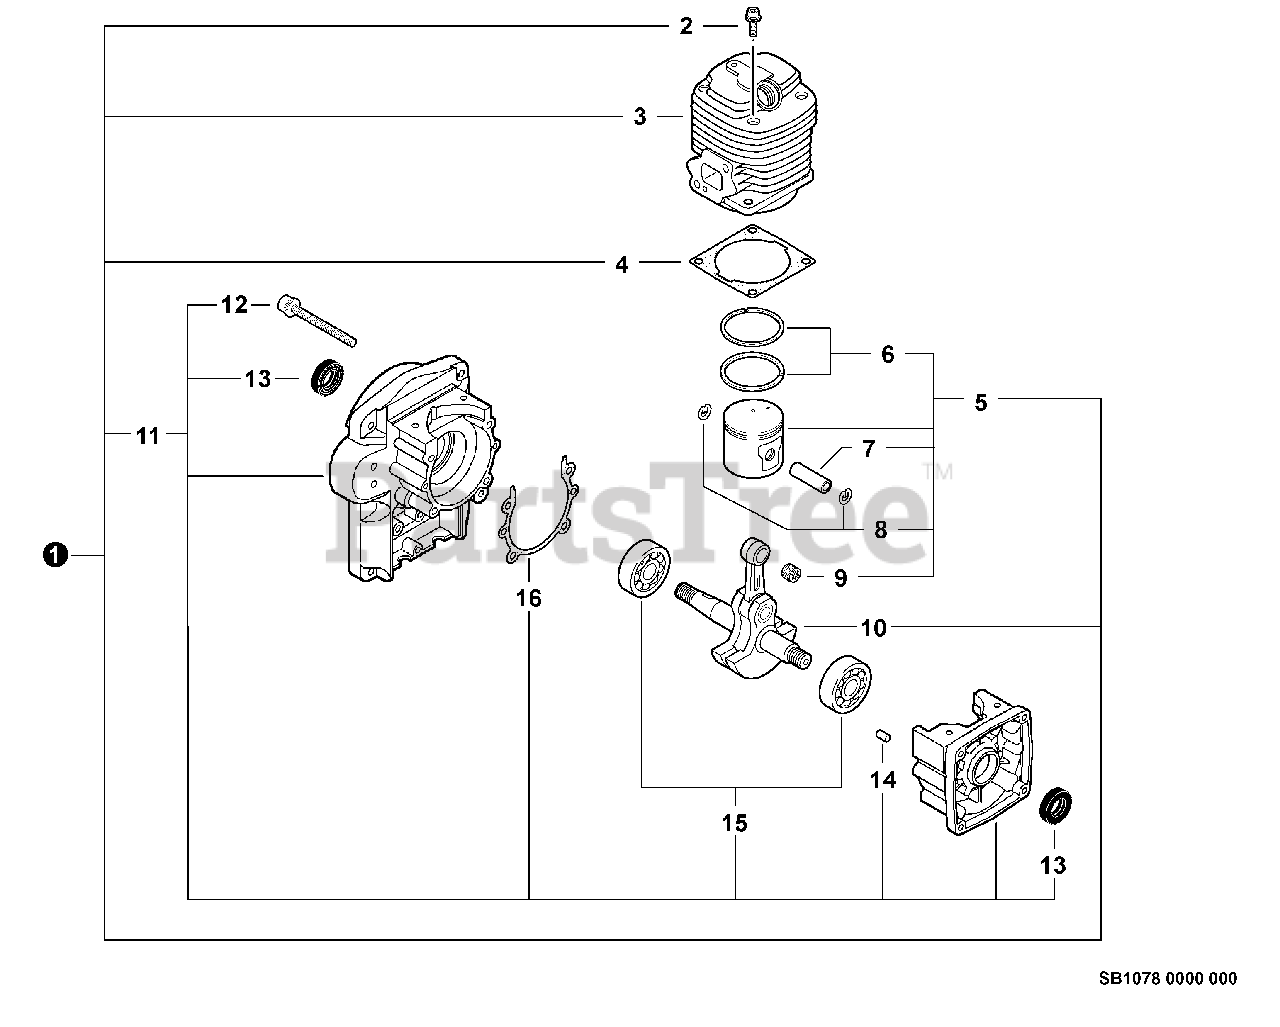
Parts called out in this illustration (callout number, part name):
1	SHORT BLOCK
2	BOLT 5×22
3	CYLINDER
4	GASKET, CYLINDER
5	PISTON KIT
6	RING, PISTON
7	PIN, PISTON
8	RING, SNAP 8
9	BEARING, NEEDLE 10
10	CRANKSHAFT ASSY
11	CRANKCASE KIT
12	BOLT 5×40
13	SEAL, OIL
14	PIN, LOCATING 4
15	BEARING, BALL 6202
16	GASKET, CRANKCASE
